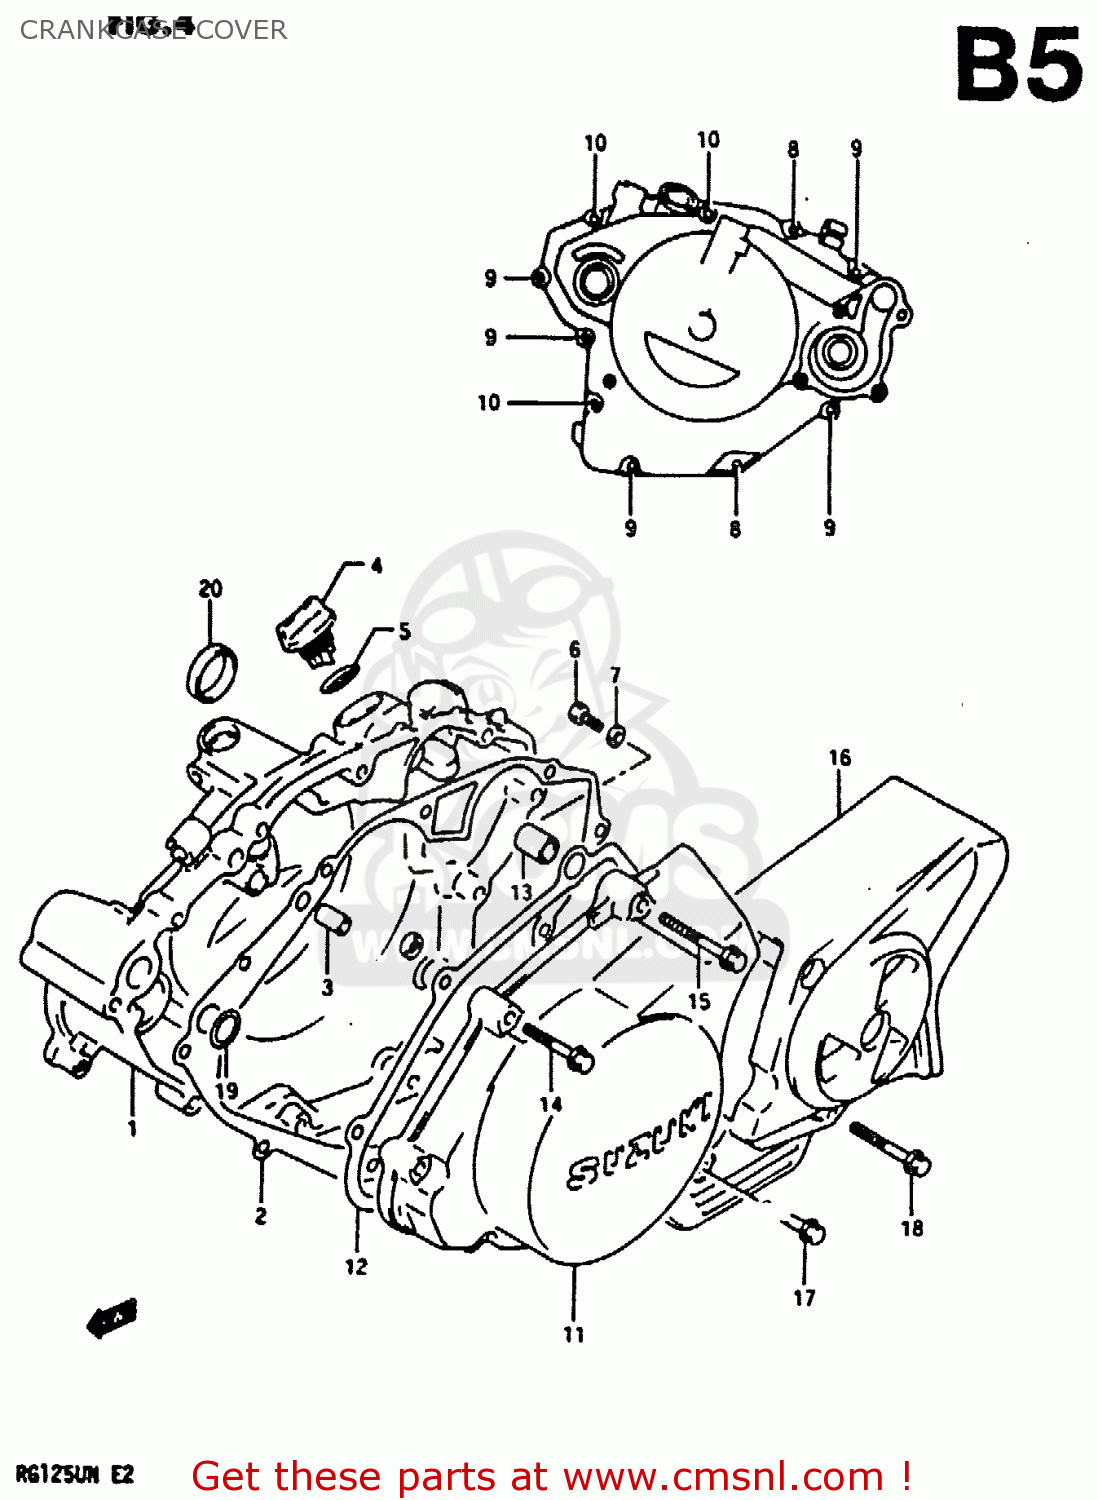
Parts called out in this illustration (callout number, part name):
1	COVER, CLUTCH
2	GASKET, CLUTCH COVER (MCA)
3	PIN
4	PLUG,OIL FILLE
5	O RING(D:3.1,ID:16.8)
6	SCREW(6X10)
7	GASKET(6.2X11X1) (NAS)
8	BOLT
9	BOLT
10	BOLT
11	COVER, MAGNETO
12	GASKET,MAGNETO COVER (NAS)
13	PIN
14	BOLT
15	BOLT
16	COVER, ENGINE SPROCKET
17	BOLT
18	BOLT
19	O RING(D:1.9,ID:14.5)
20	PLUG,CLUTCH COVER KICK
